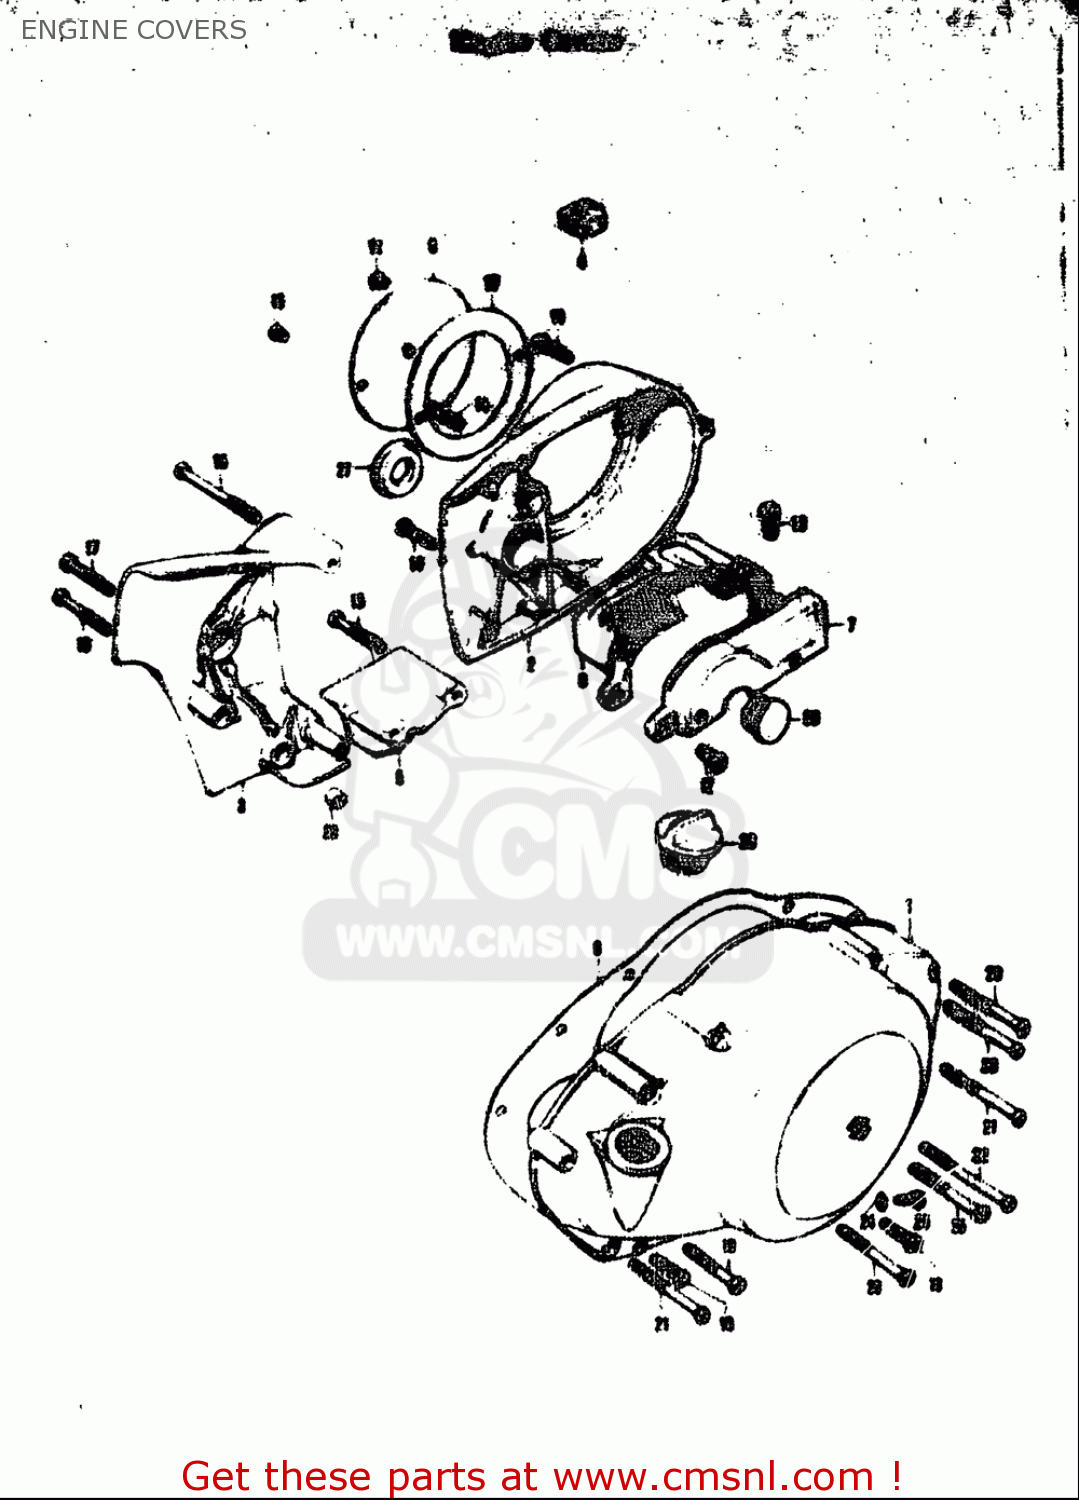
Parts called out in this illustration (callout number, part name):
9	GASKET,CLUTCH COVER (NAS)
10	GASKET,OIL PAN
13	SCREW
15	SCREW
18	SCREW
19	SCREW
20	SCREW
21	SCREW
22	SCREW
23	PIN
24	GASKET(6.2X11X1) (NAS)
26	CAP(OD:26)
27	CAP(OD:36)
28	PLUG SET
